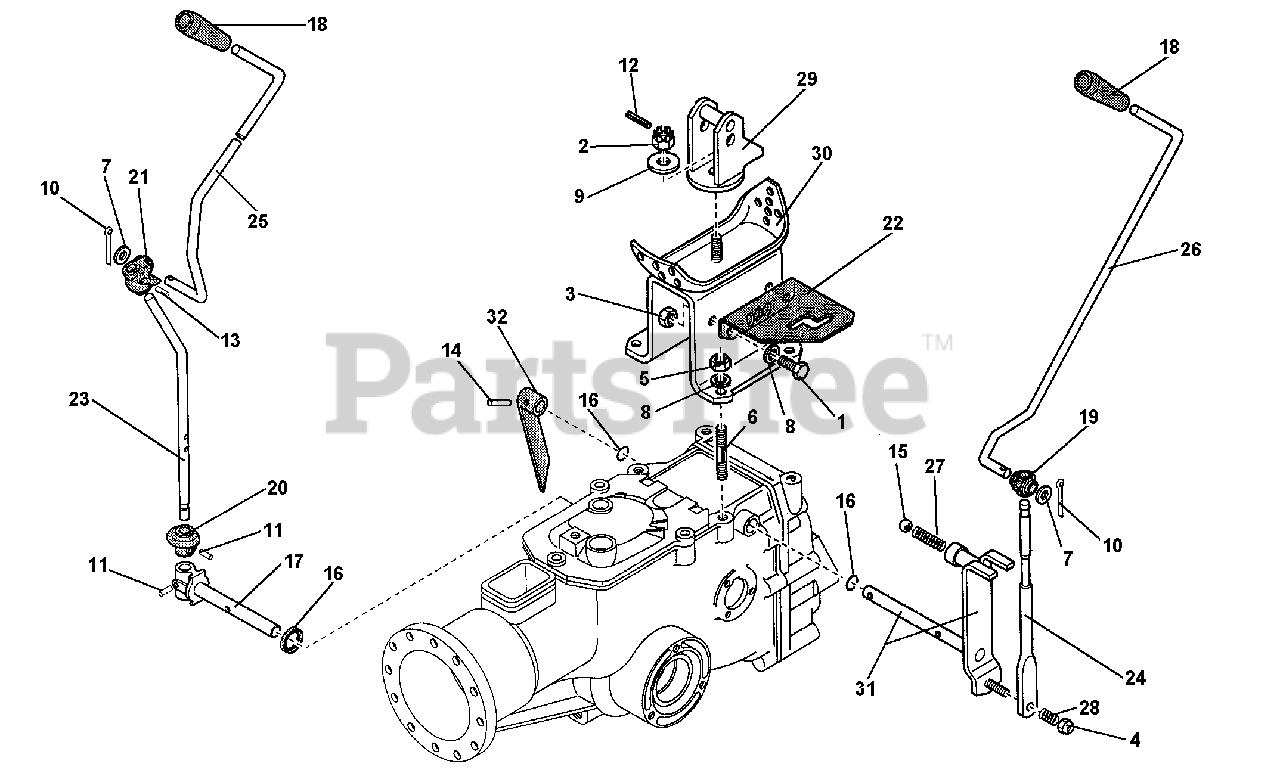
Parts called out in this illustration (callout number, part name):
1	SCREW, M8X20
2	NUT, CASTLE, M12
4	NUT, SELF LOCKING, M8
6	STUD, M8X38X14X20
7	WASHER, M10.5
8	SUPER WASHER
9	LOCK WASHER, M13
11	PIN, LOCKING, M4X20
12	PIN, LOCKING, M3X22
13	PIN, LOCKING, M4X24
14	LOCKING PIN, 6X20 SPIRAL
15	BALL, 15/32"
16	OIL SEAL, 14X22X4
19	ARTICULATOR
20	PTO STOP RING
21	PTO ARTICULATION
22	GEAR SELECTOR, 710
23	PTO CONTROL LEVER
24	SPEED CONTROL LEVER
25	PTO CONTROL ROD, ELECTRIC START
26	SPEED CONTROL ROD, 710, ELECTRIC START
29	HANDLE BAR SUPPORT
30	HANDLE BAR ANCHOR
31	SPEED CONTROL LEVER, 710
32	PTO LOCKOUT LEVER, 710
